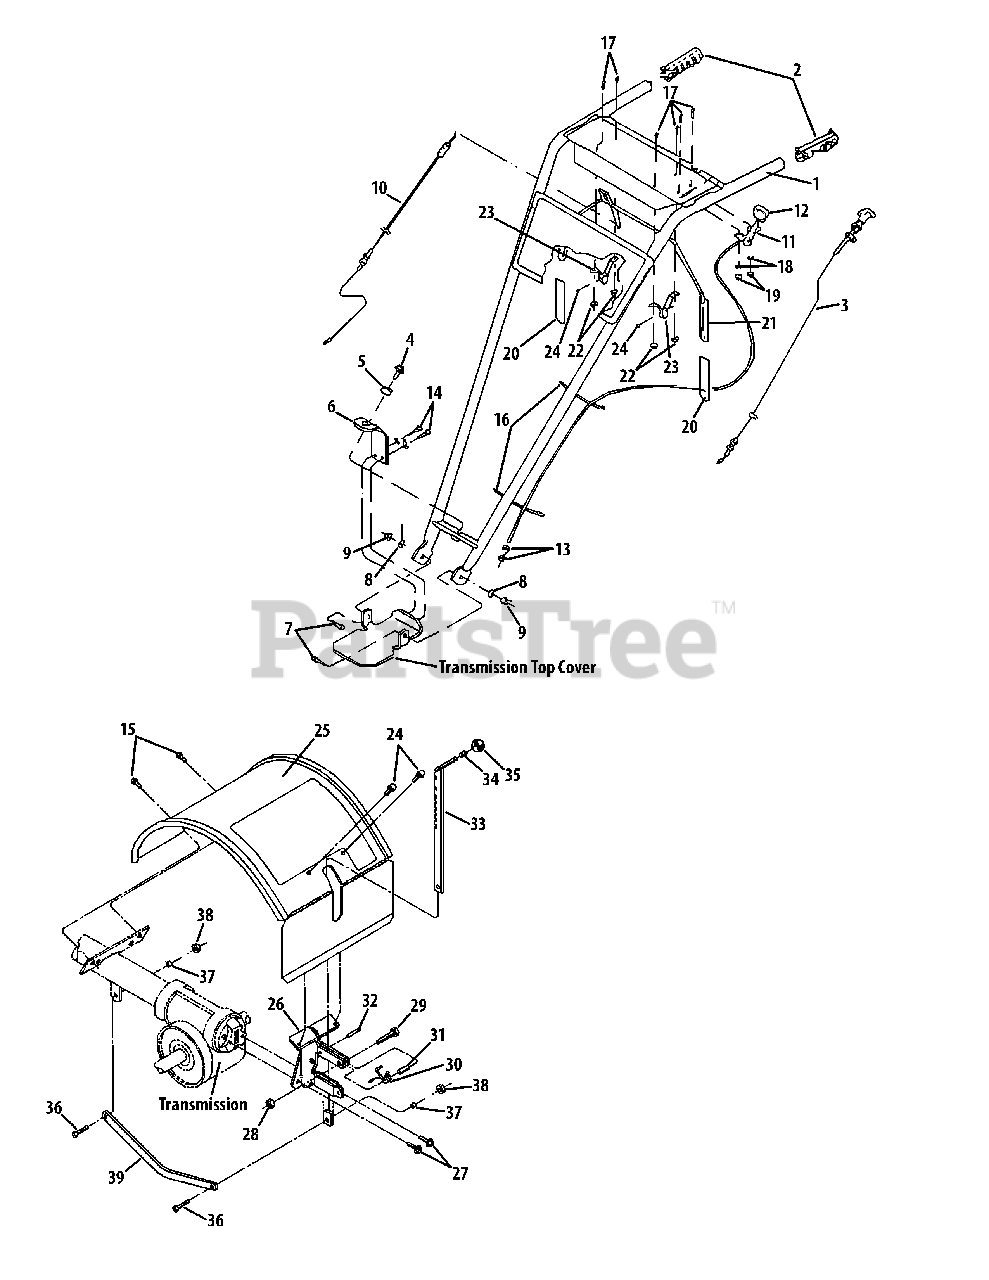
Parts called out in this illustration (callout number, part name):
1	Handlebars
3	Reverse Clutch Control Cable
4	Hex Flange Screw, 3/8-16
5	Keyed Washer
6	Handlebar Hgt. Adjustment Bracket
7	Hex Hd. Screw, 3/8-16 x 1
8	Plain Washer, 3/8
9	Hex Locknut, 3/8-16
10	Forward Clutch Control Cable
11	Wheel Gear Control & Cable Ass.
12	Wheel Gear Control Lever Knob
13	Hex Nut, 5/16-24
14	Self-tapping Screw, 3/8-16 x 3/4
15	Self-tapping Screw, 5/16-18 x 5/8
16	Cable Ties
17	Round Head Screw, #10-32 x 1/2
18	Lockwasher, #10
19	Hex Nut, #10-32
21	Forward Clutch Bail
23	Bail Support Bracket
24	Self-tapping Screw, 1/4-20 x 1/2
26	Hood Bracket
27	Hex Flange Screw, 5/16-18 x 5/8
28	Hex Locknut, 1/4-20
29	Hex Head Screw, 1/4-20 x 1
32	Roll Pin (spiral), 1/4 x 1
33	Depth Regulator
34	Retaining Ring
35	Depth Regulator Knob
36	Hex Head Screw, 3/8-16 x 1-1/4
37	Drag Bar Bushing
38	Hex Nut, 3/8-16
